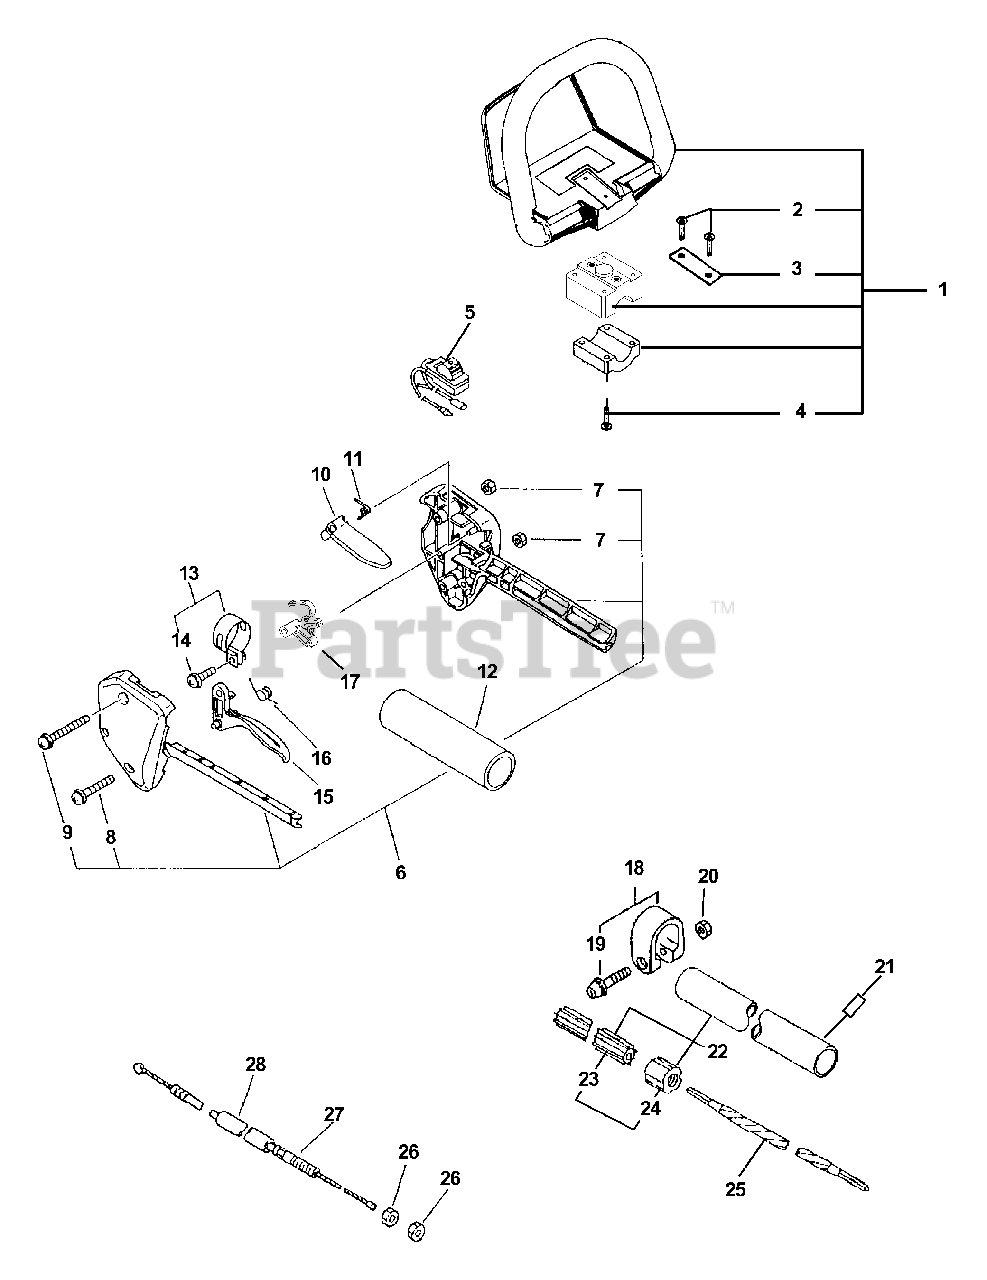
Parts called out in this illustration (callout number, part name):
1	HANDLE ASSY - FRONT
2	SCREW - 5X30
4	SCREW - 5
5	IGNITION SWITCH ASSY
6	CONTROL HANDLE ASSY
8	SCREW - 5X25
9	SCREW - 5X35
10	LEVER, TRIGGER LOCKOUT
11	SPRING, LOCKOUT LEVER
12	GRIP, HANDLE - REAR
13	CLAMP KIT
14	SCREW - 5X14
15	TRIGGER, THROTTLE
16	SPRING, TRIGGER
17	LOCKOUT, THROTTLE
18	CLAMP
19	SCREW - 5X28
21	LABEL - ALIGNMENT
22	MAIN PIPE ASSY
23	LINER - FLEXIBLE
25	DRIVESHAFT - FLEXIBLE
27	CABLE, THROTTLE
28	TUBE, PROTECTIVE - CORRUGATED
